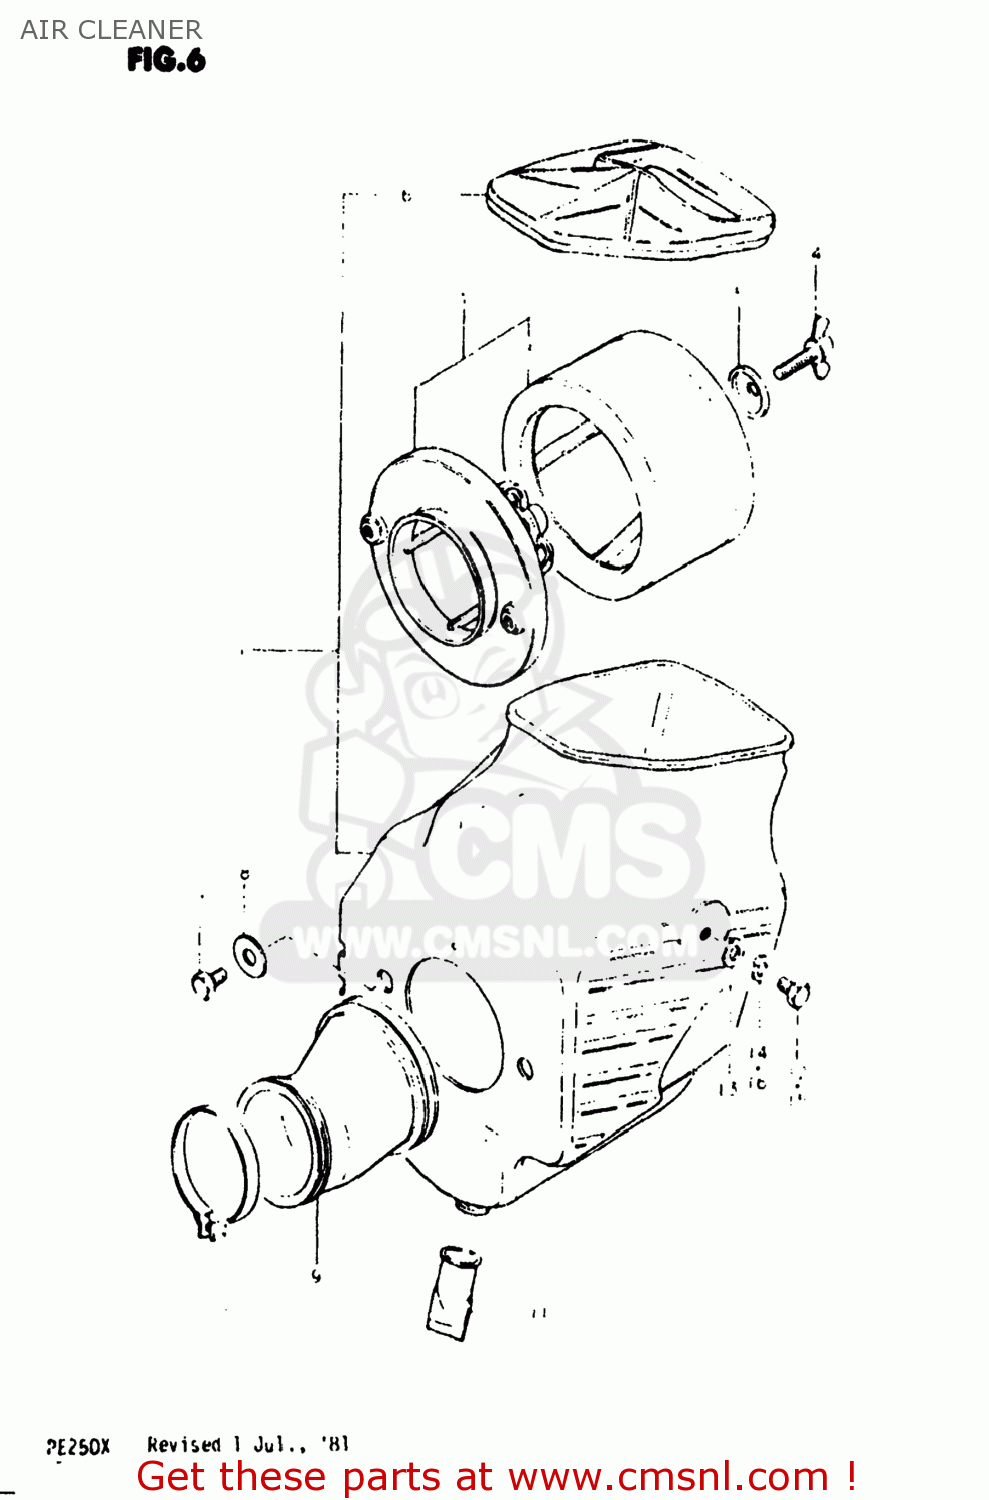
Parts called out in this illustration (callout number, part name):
1	CLEANER ASSEMBLY,AIR
2	FILTER ASSY
3	FILTER
4	WING BOLT,AIR CLEANER
5	HOLDER,FILTER
6	CAP,AIR CLEANER
7	BOLT
8	SPACER,AIR CLEANER,REAR
9	TUBE,AIR CLEANER OUTLET
10	CLAMP
11	HOSE,DRAIN
12	BOLT
13	WASHER
14	LOCK WASHER
15	SCREW
16	LOCK WASHER
